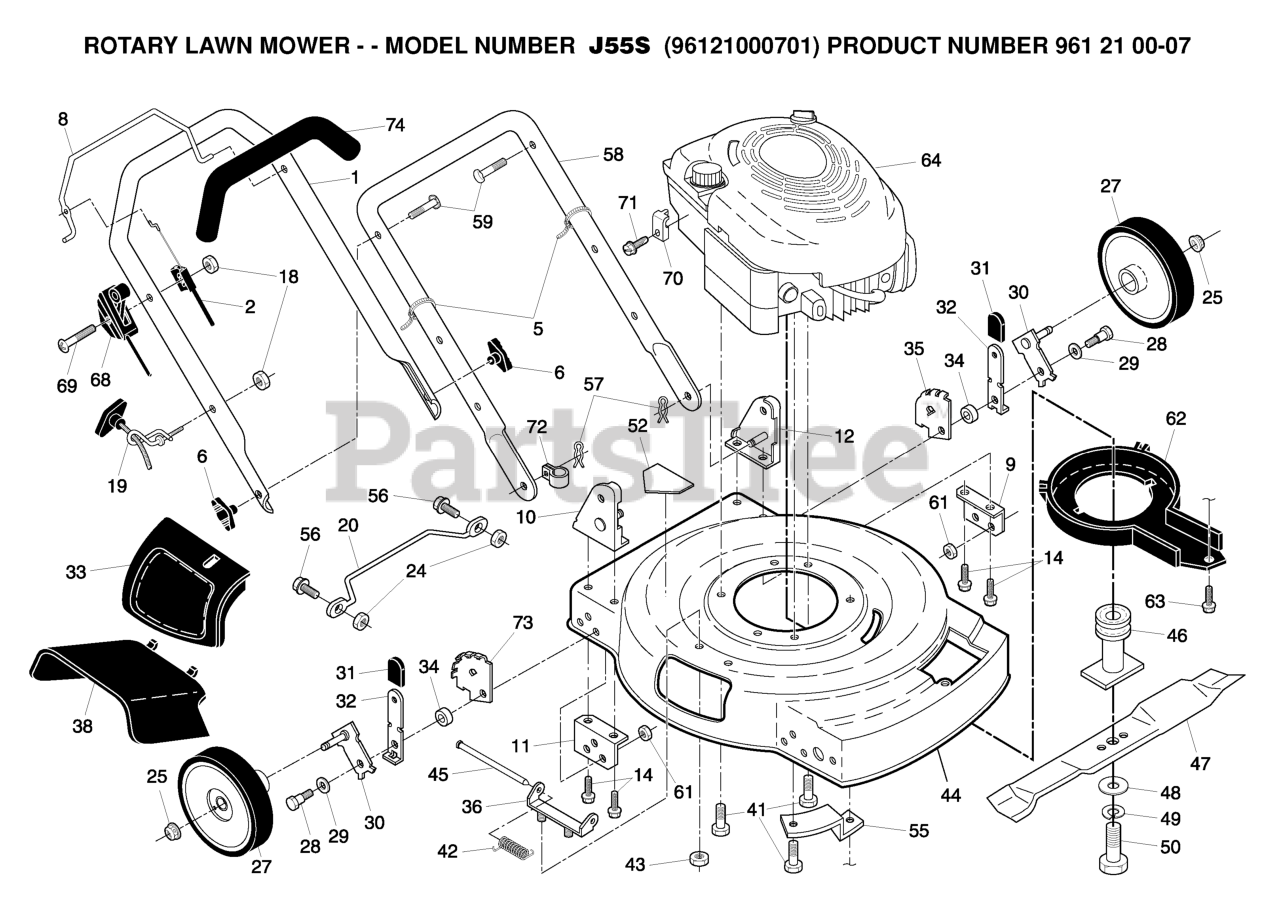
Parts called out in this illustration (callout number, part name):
1	HANDLE.UP.DLX.COMF.W/GRIP.GREY
2	ENGINE ZONE CONTROL CABLE
5	TIE GUIDE
6	KNOB, DEFLECTOR
8	BAIL.COMF.FWGD.668.ORANGE.WALK
9	GUARD.SLKSCR.BELT.
10	HANDLE BRACKET ASM. RH
11	Support Bracket, Handle, RH
12	HANDLE BRACKET ASM. LH
14	SCREW.5/16-18X3/4
18	NUT
19	RB GUIDE.ROPE.STD.BLK.ZIN WSL
25	HEX FLANGE LOCKNT
27	WHEEL 8X1.75 MAG2 RAD3
28	BOLT
29	WASHER.BELLEVILLE (3 2 LB)
30	AXLE ARM
31	SELECTOR KNOB
33	DOOR.MULCH.22.EZ.MULCH.GREY
34	RP SPACER HT ADJ
35	BRACKET WHL ADJ
36	BRACKET.ASM.HOUSING.EZ.MUL
38	DEFLECTOR.GUARD.22..EZ.MULCH
41	BOLT 3/8-16X1-1/8
42	TORSION SPRING
43	LOCKNUT.NYLOC.1/4-20
44	Kit, Mower Housing
45	ROD.HINGE.COMBI-C
46	BLADE ADAPTOR / PULLEY
47	Blade, 22"
48	WASHER,HARDEN
49	LOCKWASHER
50	SCREW, HEX HD 3/8-24 X 1-3/8
52	DECAL.INTERNATIONL.CUTFINGER
55	BRACKET
56	REPL BY 817 02 10-08
57	HAIRPIN COTTER
58	HANDLE
59	BOLT, HANDLE 5/16-18X1.75
61	LOCKNUT PM
62	DEBRIS.SHIELD.21:.FGD
63	SCREW.HEX.WSH
68	THROTTLE CONTROL
70	CABLE CLAMP(ENGINE)
71	SCREW.HEX.HEAD.WASHER.10-16
72	CLIP.CABLE.BLK
73	BRACKET WHL ADJ. NLA
74	GRIP.HANDLE.FOAM
